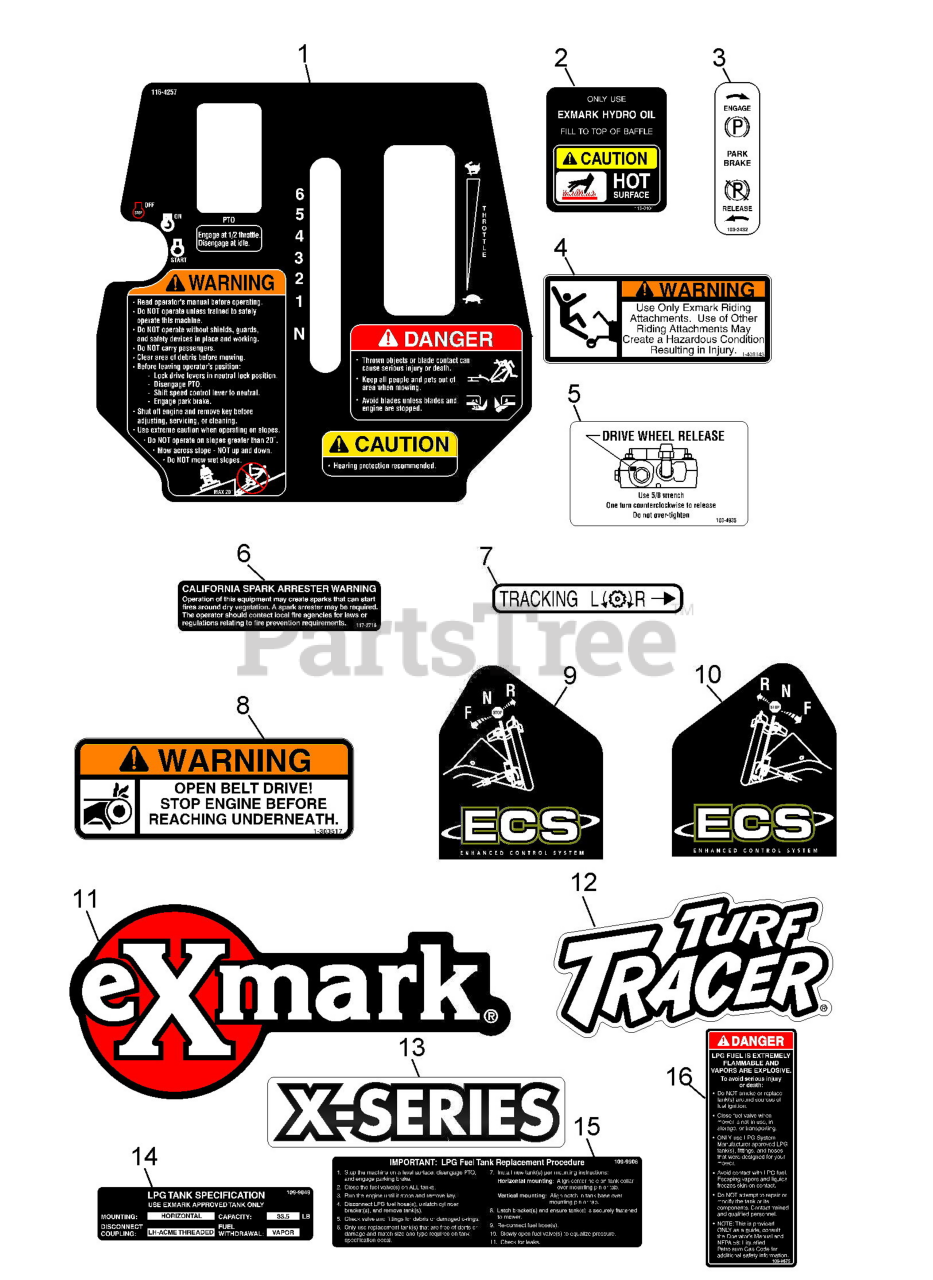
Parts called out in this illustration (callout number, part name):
1	DECAL,CONSOLE TTX
2	DECAL-HYDRAULIC TANK
3	DECAL,SULKY WARNING
4	DECAL,PARKING BRAKE
5	DECAL,DRIVE RELEASE
6	DECAL-ARRESTER, SPARK
7	DECAL,TRACKING ADJUST
8	DECAL,BELT DRIVE
9	DECAL,LH ECS INSTRUCTION
10	DECAL,RH ECS INSTRUCTION
11	DECAL,EXMARK LOGO
12	DECAL,TTH MODEL
13	DECAL-X-SERIES
14	DECAL,LPG TANK SPEC HORIZ
15	DECAL-TANK REPLACEMENT
16	DECAL-LPG WARNING
